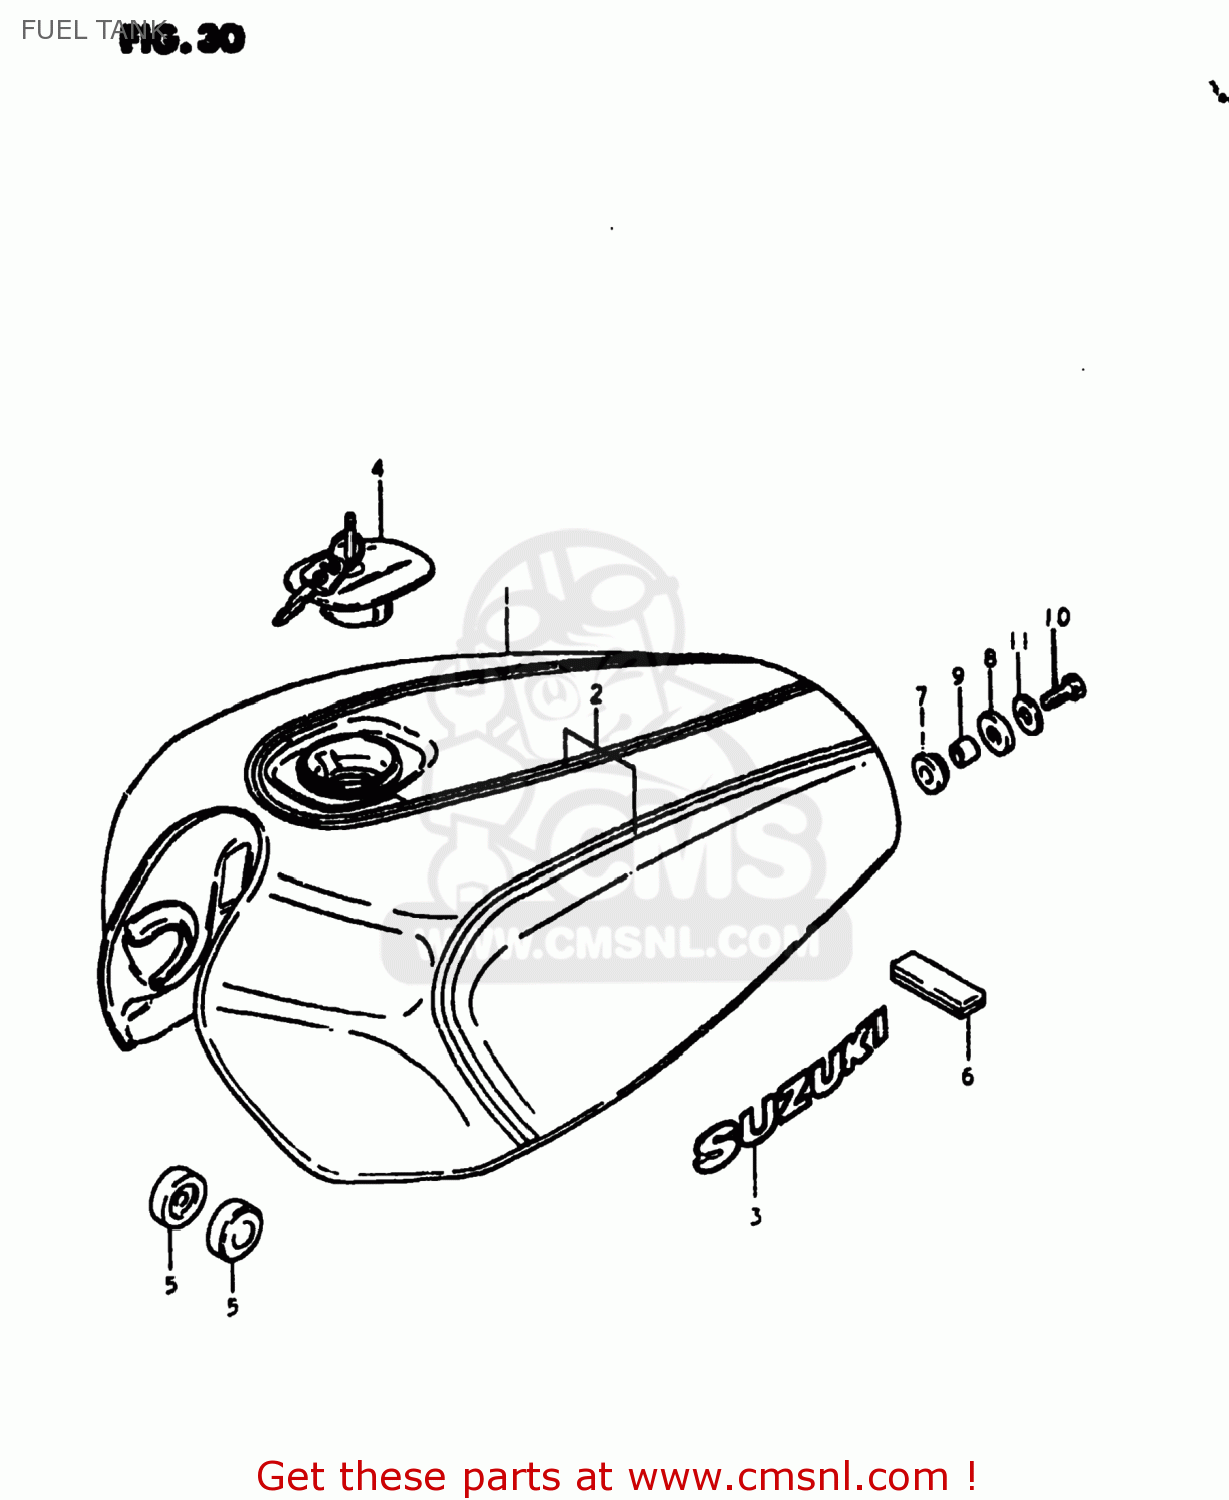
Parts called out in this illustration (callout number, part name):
1	TANK ASSEMBLY,FUEL
2	TAPE SET
3	EMBLEM
4	CAP SET,FUEL TANK
5	CUSHION
6	CUSHION
7	CUSHION
8	CUSHION
9	SPACER(8.5X12X19)
10	BOLT (8X30)
11	WASHER (8.5X29X1.6)
